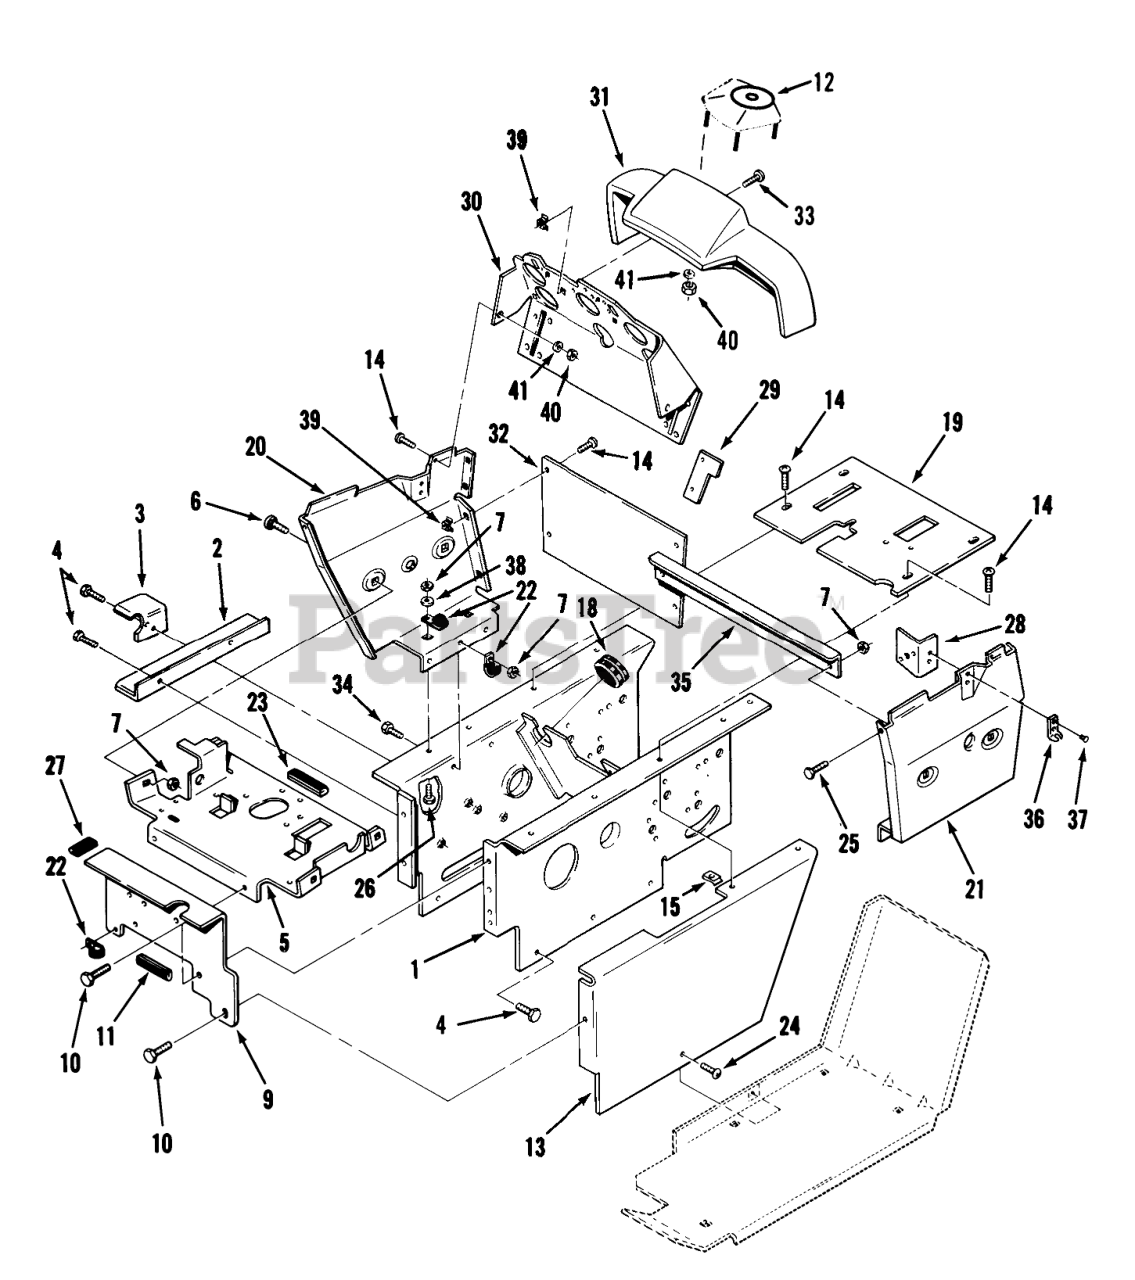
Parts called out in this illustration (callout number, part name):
1	Hoodstand
2	ANGLE-BELT GUARD B
3	BRCKET-BLT SUTB
4	SCREW
4	Bolt
5	SUPPORT-BATTERY B
6	Bolt
7	Nut
9	PLATE-FRT HOODSTA B
10	SCREW
11	EDGE TRIM 2" 102896
12	COVER-STEERING SHAFT
13	Cover-Side LH
13	COVER-L.H. R
14	SCREW-PPH
18	GROMMET
19	Shift Cover Plate 516 & 518
19	Shift Cover Plate 520-H
19	Shift Cover Plate 520-HC
20	Panel-RH
21	LS Panel
21	PANEL-SIDE LS B
22	CLIP
23	EDGE TRIM 5" OF 102896
24	Screw
24	WASHER 5/16 SAE
25	H H C S
26	CARRIAGE BOLT -4
27	DECAL-TACHAMATIC
28	BRACKET-SWITCH SU
29	STOP-CHOKE
30	PANEL ASSY OB
30	PANEL ASSY B
31	Console Cover Kit-516 (Contains #115621 2-gauge cover, #115659 Steering Cover, (4) #915661 Nuts 1/4-20 & (4) 920007 Lockwashers)
31	CONSOLE ASSY
32	PLATE-HOODSTAND B
32	Plate-Hoodstand
33	SCREW 1/4-20X.87
34	Bolt
35	STIFFENER-PANEL B
36	Latch Keeper (included in 106825 Hood Latch)
37	RIVET
37	RIVET -4
38	WASHER 5/16 SAE
39	Nut 1/4-20
40	Nut
